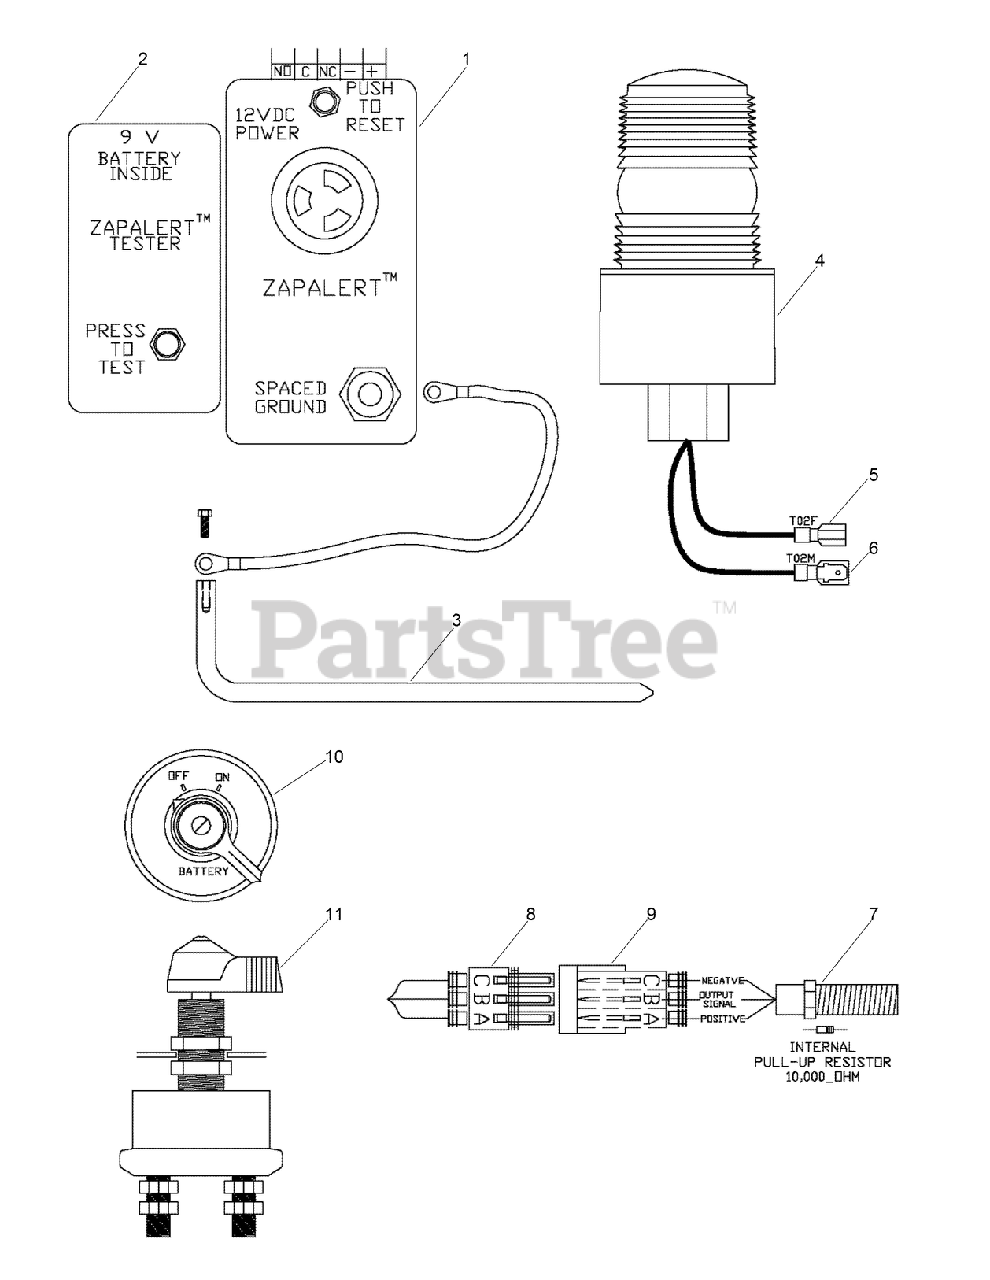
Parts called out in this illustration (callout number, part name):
2	TESTER-ZAPALERT
3	GROUND STAKE - Zap Alert
4	ASSEMBLY - Strobe, Small
5	DISCONNECT - 16-14 Nylon Blue
6	TERMINAL - Male Tab, 16-14 Nylon Blue
7	SPEED PICKUP - for 8HM24053 Mud Pump
8	CONNECTOR - 3 Socket
9	CONNECTOR - 3 Pin, Weatherpack
10	FACEPLATE-BATTERY, ON/OFF
11	SWITCH-BATTERY (1000 AMP)
